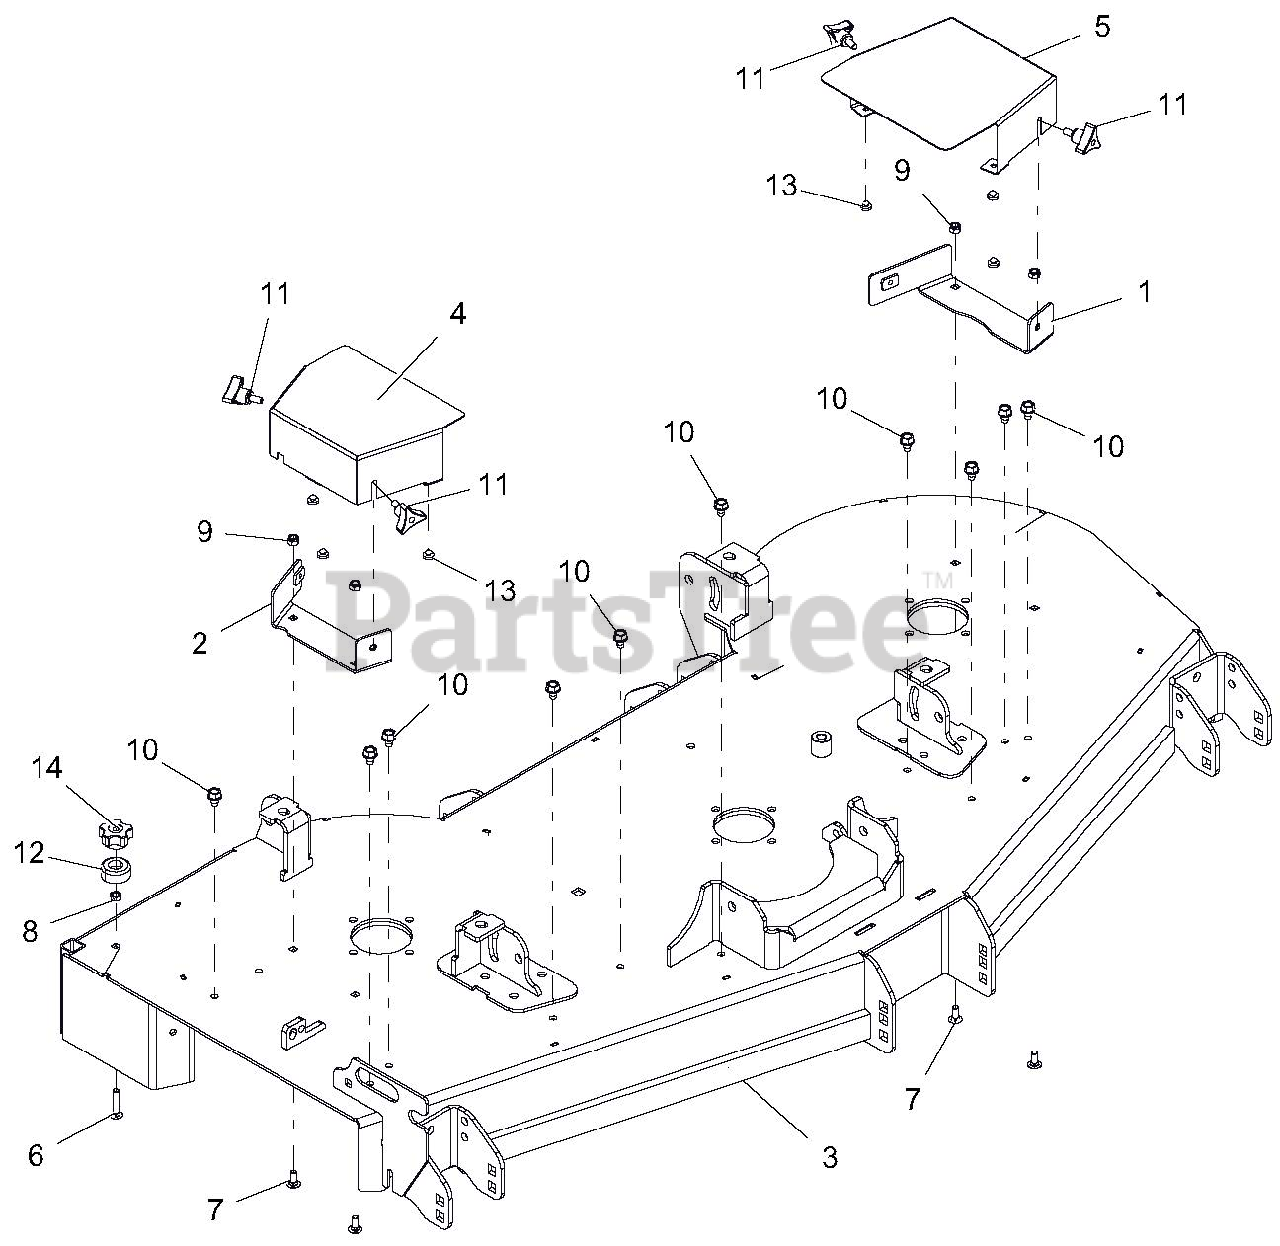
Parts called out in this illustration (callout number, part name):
1	WLDMT, RH BRKT BELT GUARD MOUNTING-RED
2	WLDMT, LH BRKT BELT GUARD MOUNTING-RED
3	WLDMT, 60 IN DECK WITH DECALS
4	GUARD, RH DECK BELT
5	GUARD, LH DECK BELT-RED
6	BLT-RDHDSQNK .31-18X1.50 G5 YWZC
7	BLT-RDHDSQNK .31-18X.75 G5 YWZC
8	NUT-LK-CTR .31-18 YWZC
9	NUT-LK-NYL .312-18 YWZC
10	SCR-TAP .38-16X.50 HWH TR YWZ
11	KNOB, WING STUD .312-18X.75
12	BUMPER, RECESSED 1.50 X .63 W/.31 HOLE
13	BUMPER GROMMET .125 X .25 REV
14	KNOB, CLAMPING
